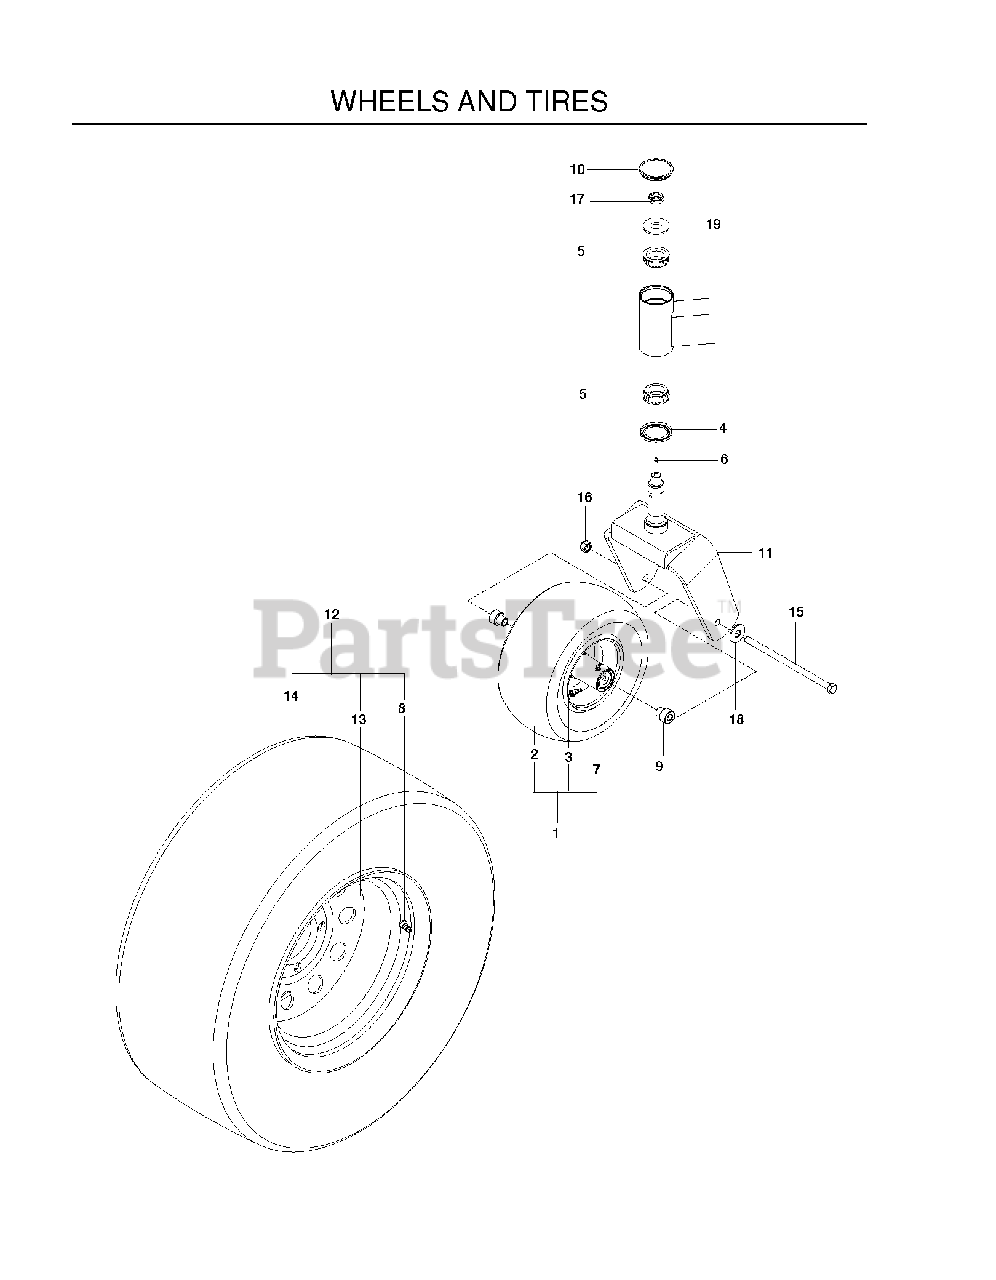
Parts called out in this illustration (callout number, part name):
1	FRONT TIRE ASSY
2	TIRE - SMOOTH 13X6.50-6
4	SEAL, BEARING
5	CONE, LM67048
7	ZERK
8	VALVE STEM TR-412
9	AXLE SPACER
11	FORK.CASTER.ORANGE
12	WHEEL/TIRE.ASM SILV 23X10.5-12
13	RIM, 12 X 8.5, 1.125" NEG OS
14	TIRE.TURF.MASTER.23X10.5-12
15	HEX SCREW 1/2-13 X 9.5 GR5
16	NUT, 1/2-13 HEX FLG NYLOC ZD
17	NUT, 3/4-16 HEX THIN NYLOC ZD
18	WASHER 1/2" FLAT
19	WASHER, 3/4 HARDENED
